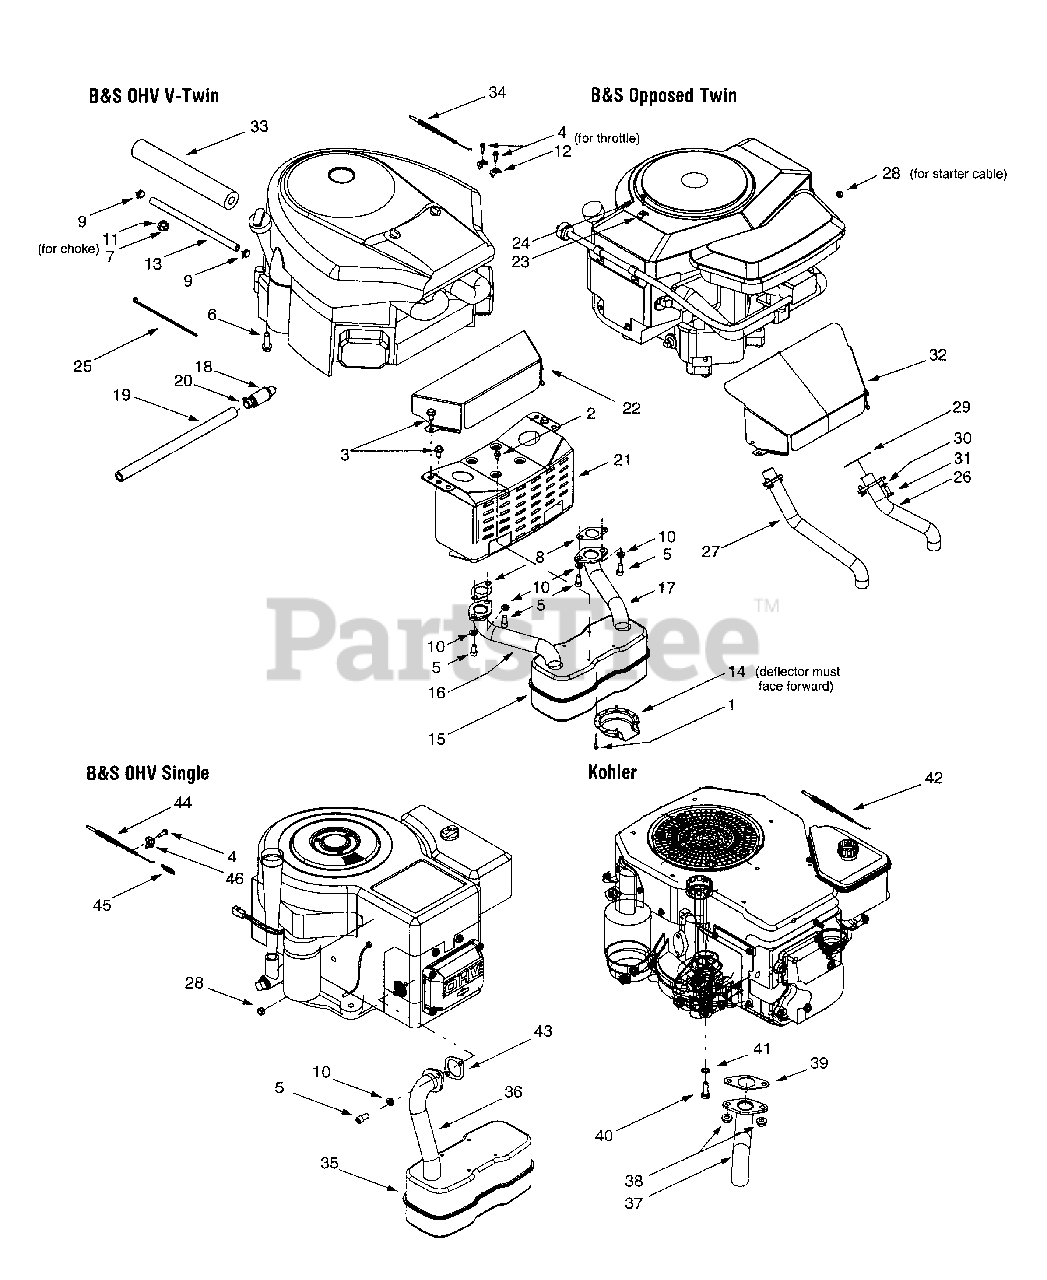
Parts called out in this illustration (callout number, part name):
1	Self-tapping Screw, #8-32 x .375
2	Self-tapping Screw, 1/4-20 x .5
3	Self-tapping Screw, 5/16-18 x .625
4	Screw, #10-32 x .625
5	Socket Cap Screw, 5/16-18 x .625
6	Self-tapping Screw, 3/8-16 x 1.25
7	Hex Nut, 3/8-16
8	Exhaust Gasket
9	Hose Clamp
10	Lock Washer, 5/16
11	Lock Washer, .406 x .875 x .059
12	Casing Clamp
13	Fuel Line Hose
14	Muffler Deflector
15	Muffler, Twin Inlet
16	RH Exhaust Pipe
17	LH Exhaust Pipe
18	Oil Drain Valve
19	Oil Drain Hose
20	Oil Drain Cap
22	Engine Heat Shield
23	Clamp, 9/16
24	Screw, #10-16 x .5
25	Cable Tie
26	LH Exhaust Pipe
27	RH Exhaust Pipe
28	Hex Sems Nut, 1/4-20
29	Exhaust Gasket
30	Lock Washer, 1/4
31	Hex Screw, 1/4-20 x .620
33	Foam, .625 x 1.5 x 10
34	Throttle Cable
35	Muffler, Single Inlet
36	Exhaust Pipe
37	Exhaust Pipe
38	Flange Nut, 8mm
39	Exhaust Gasket
40	Hex Cap Screw, 8mm
41	External Lock Washer
42	Throttle Cable
43	Exhaust Gasket
44	Throttle Cable
45	Extension Spring, .275 x 1.25
46	Casing Clamp
